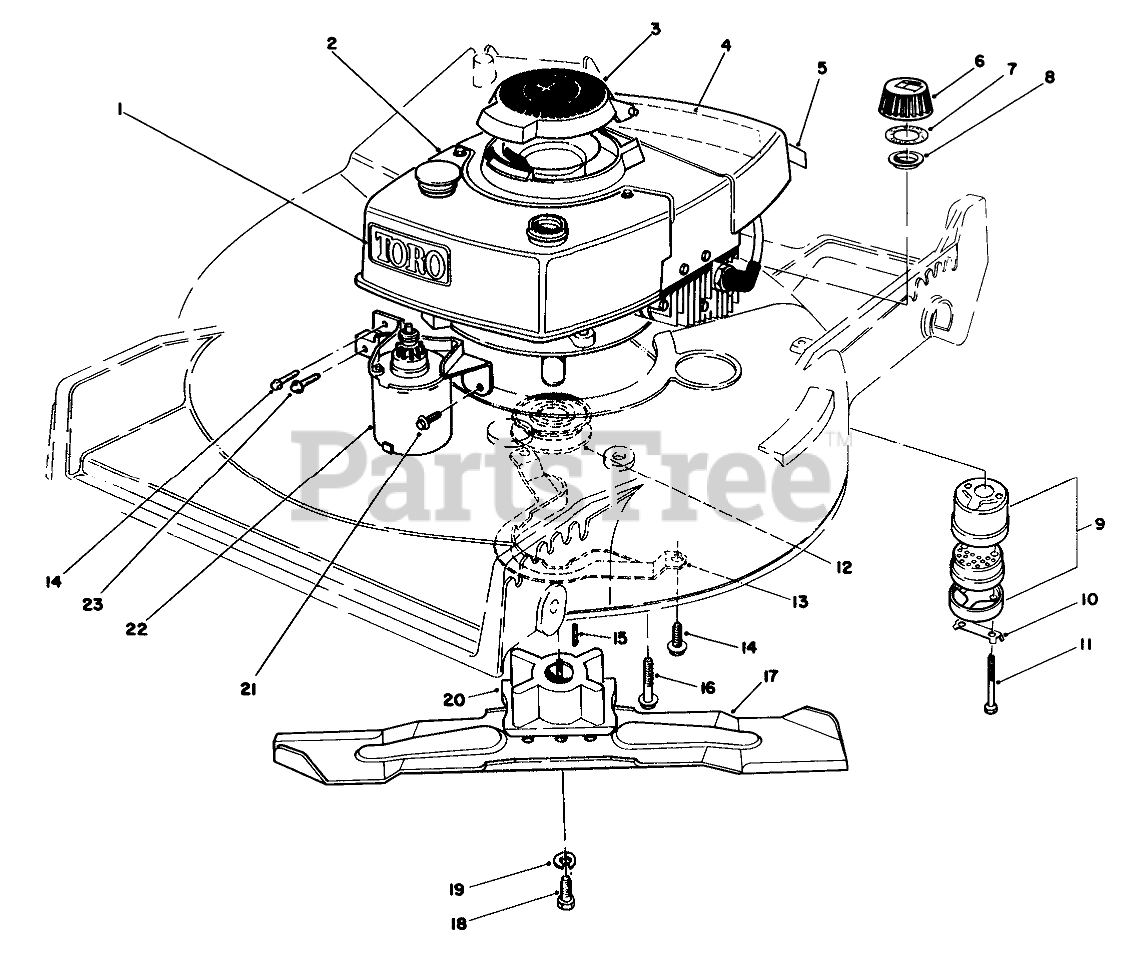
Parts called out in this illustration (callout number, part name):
1	Decal Tow
2	Engine
3	COVER ASM
4	Decal Maintenance
5	Decal-Primer Bulb
6	Gas Cap (Incl. Ref. #7 & 8)
7	GASKET
8	GAS CAP BAFFLE
9	Muffler Assembly (Incl. Ref. #10 & 11)
10	CLIP - LOCKING
11	SCREW-HH
12	Pulley
13	BELT GUIDE
14	Screw
15	KEY-SQUARE
16	3/8-16 X 2 CAPSCREW
17	BLADE-21in
18	SCREW-BLADE
19	WASHER-LOCK
20	BLADE RETAINER(DEEP)
21	SCREW
22	STARTER MOTOR ASM
23	SCREW AND WASHER ASM
